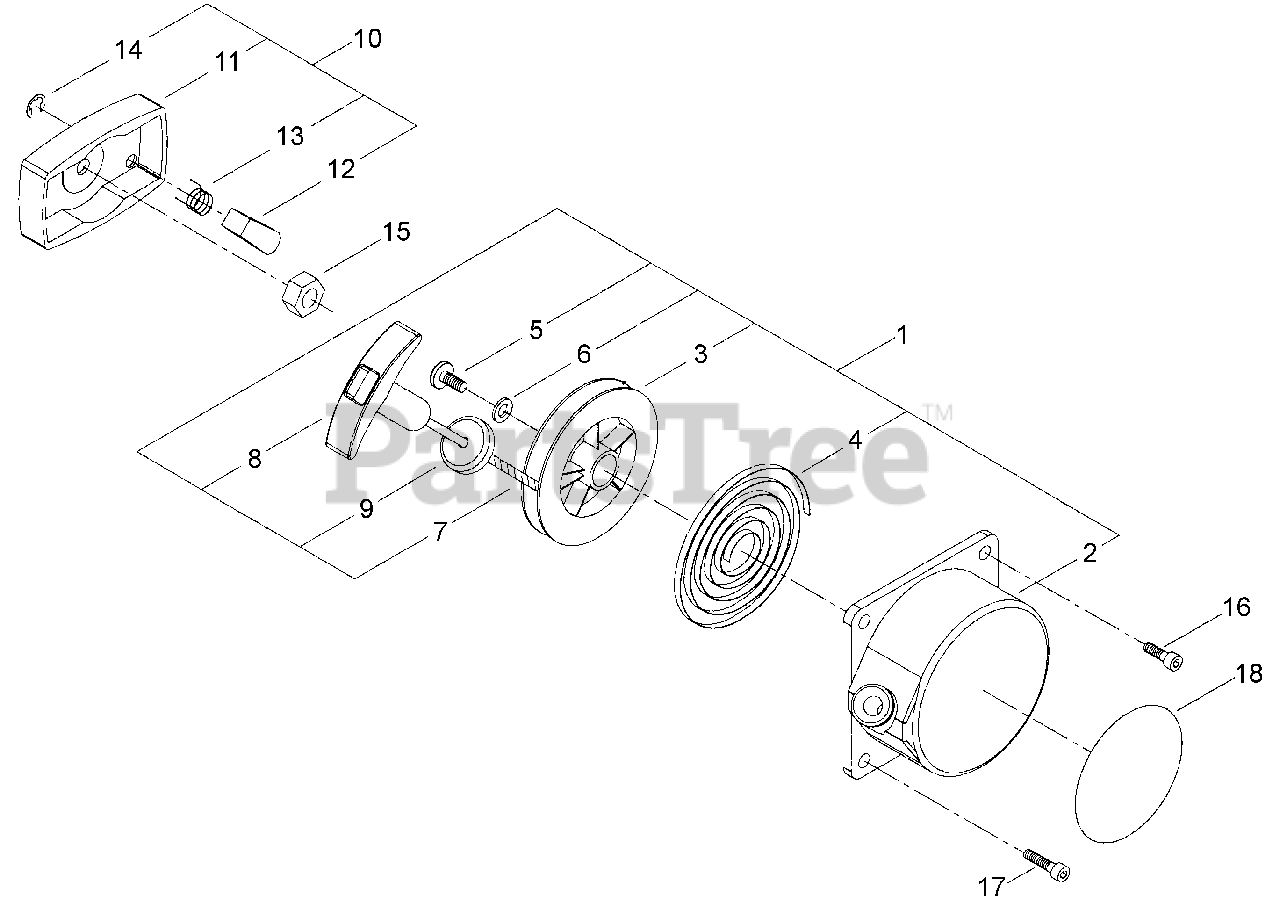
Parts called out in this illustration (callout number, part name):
1	STARTER ASSY
2	STARTER CASE
3	REEL, ROPE
4	SPRING
5	SCREW
6	WASHER
7	ROPE
8	GRIP, STARTER
9	GUIDE, ROPE
10	STARTER PAWL ASSY
11	CASE, PAWL
12	PAWL, STARTER
13	SPRING, RETURN
14	RING, RETAINING
15	NUT
16	SCREW - 5X20
17	SCREW - 5X25
18	LABEL - MODEL
